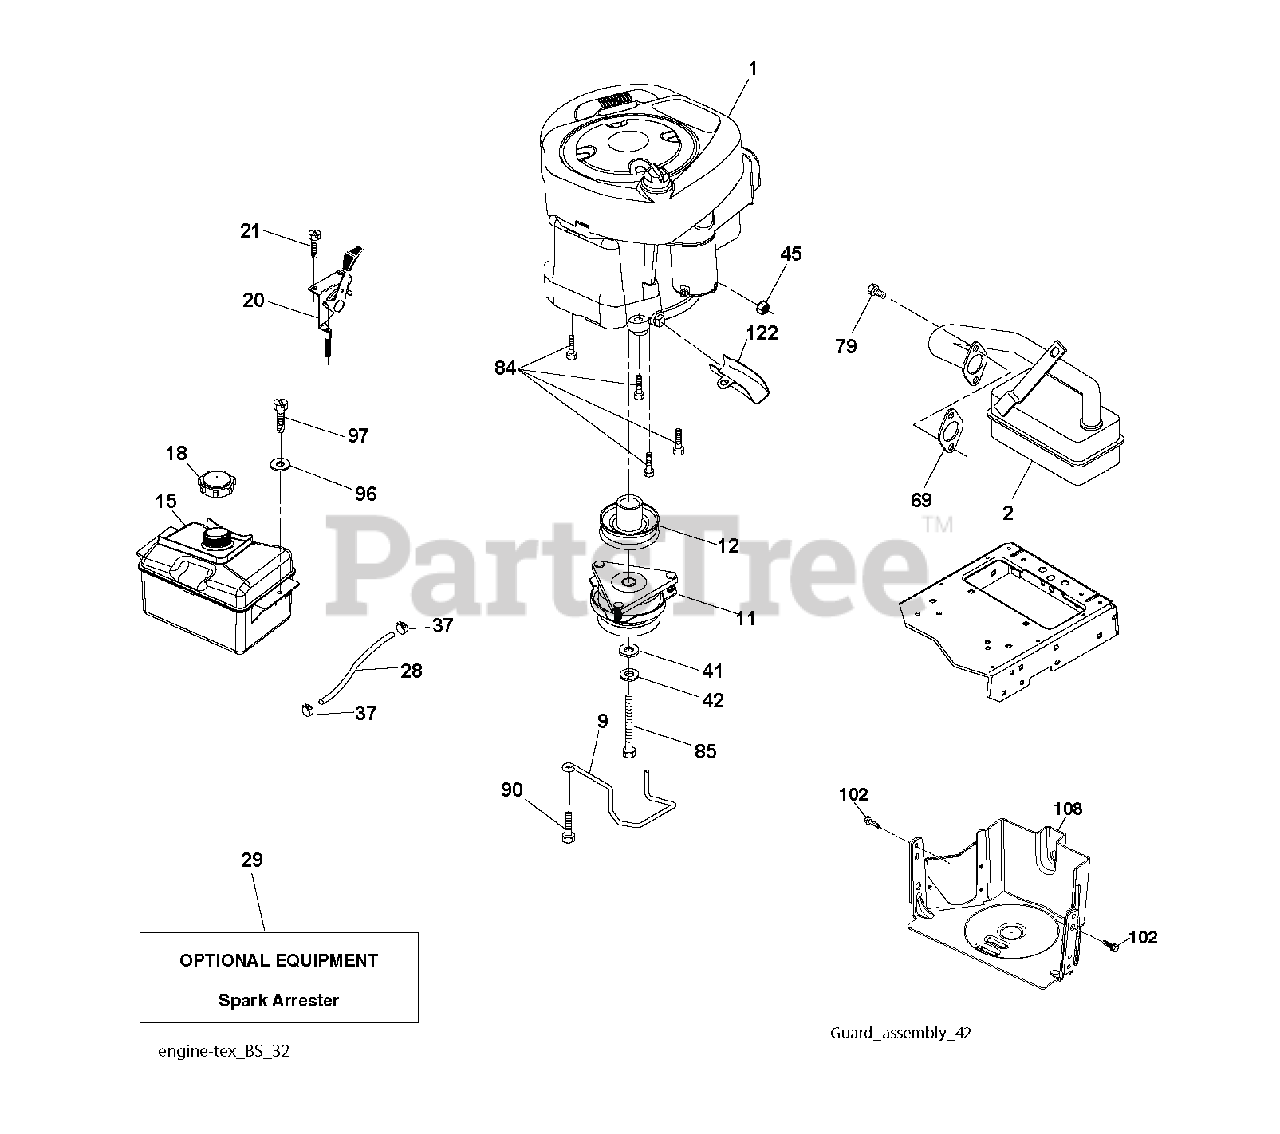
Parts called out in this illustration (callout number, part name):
9	KEEPER.BELT.ENGINE.3.25
11	CLUTCH
12	PULLEY.ASM.ENG.OGURA.3
15	TANK FUEL FRT 1.5 GAL
18	CAP ASM.FUEL.2.25"FR.
20	CONTROL.TH/CK.C.
21	SCREW.#10 X 0.750.BOS THREAD
28	LINE.FUEL.20
29	ARRESTER SPARK (OPTIONAL)
37	HOSE CLAMP
42	LOCKWASHER
45	NUT
69	REPL BY 532 27 22-93
79	SCREW.SOCKET HD.5/16-1
84	SCREW.3/8-16
85	BOLT HEX 7/16-20X4-1/4"
90	SCREW 3/8-16X1
97	SCREW HEXWSHR 1/4-20X3/4
102	SCREW
122	EXTENSION DRAIN OIL
